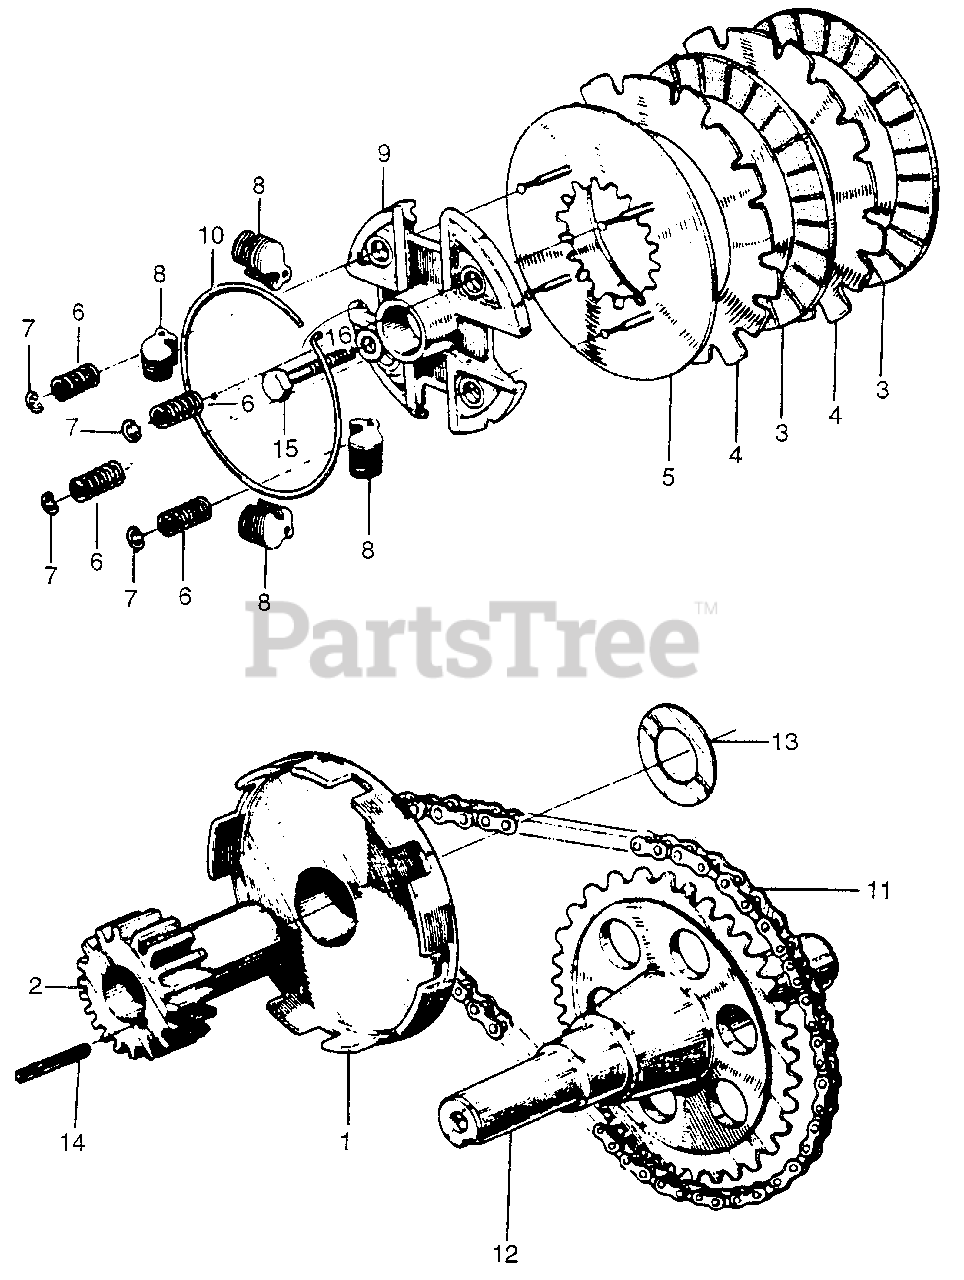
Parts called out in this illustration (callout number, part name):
1	SPROCKET, DRIVE
2	CENTER, CLUTCH (NOT AVAILABLE)
3	DISK, CLUTCH FRICTION
4	PLATE, CLUTCH
5	PLATE, CLUTCH PRESSURE
6	SPRING, CLUTCH FREE
7	HOLDER, CLUTCH SPRING
8	WEIGHT, CLUTCH
9	HOLDER, CLUTCH WEIGHT (NOT AVAILABLE)
10	CENTER, CLUTCH WEIGHT
11	CHAIN, DRIVE (RK428SH-36LE)
12	SHAFT, P.T.O. (28T)
13	WASHER (22MM) (NOT AVAILABLE)
14	KEY, CLUTCH CENTER (NOT AVAILABLE)
15	BOLT, HEX. (8X35)
16	WASHER, SPRING (8MM)
